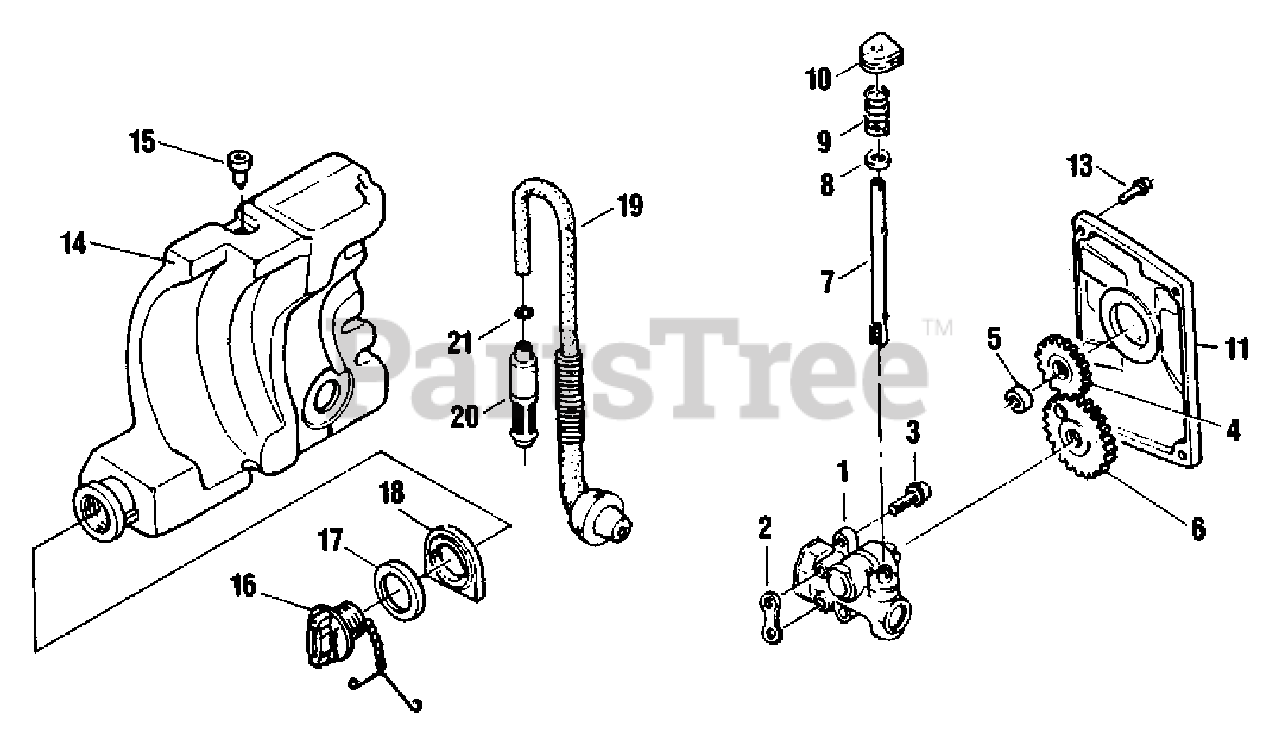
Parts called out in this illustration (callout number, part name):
1	OIL PUMP ASSY
2	GASKET, OIL PUMP
3	SCREW - 4X14
4	GEAR - PINION
6	GEAR
7	SHAFT, OIL PUMP
8	WASHER - 4
11	COVER, PUMP
13	SCREW - 4X14
14	TANK, OIL
15	VALVE, OIL
16	CAP, OIL
17	GASKET, CAP
18	TANK, OIL
19	TUBE, OIL
20	FILTER, OIL
21	CLIP
